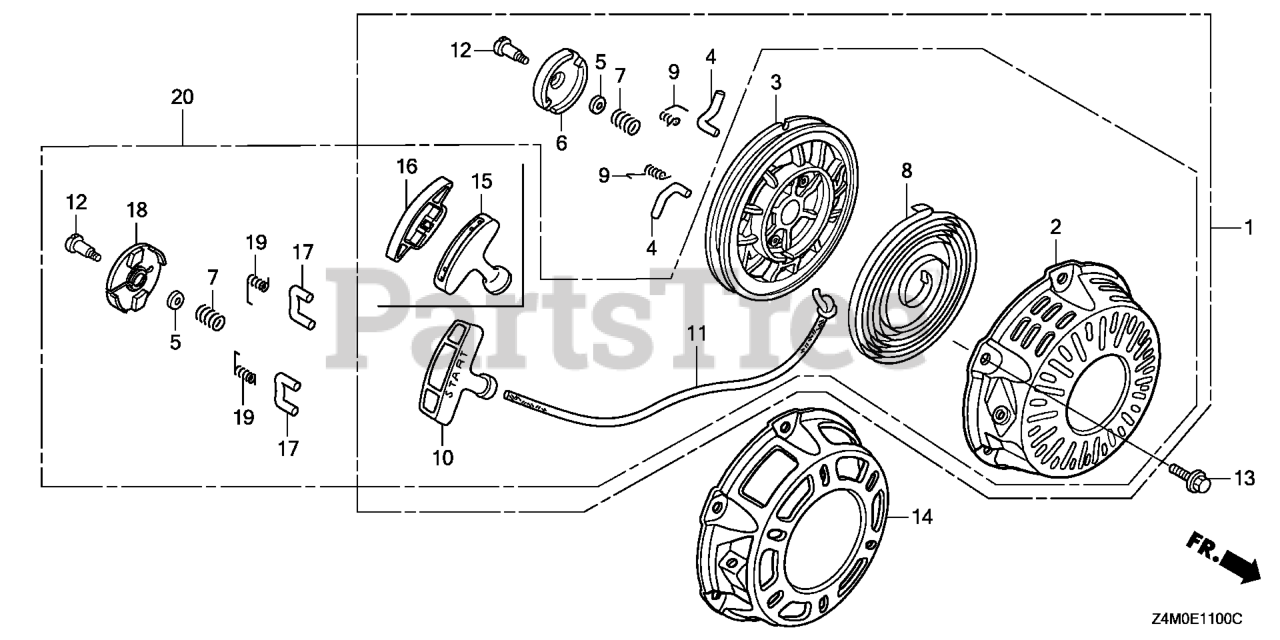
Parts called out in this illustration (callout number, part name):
2	CASE, RECOIL STARTER *R280* (POWER RED)
2	CASE, RECOIL STARTER *NH1* (BLACK)
3	REEL, RECOIL STARTER (BLACK)
5	PLATE, FRICTION
7	SPRING, FRICTION
8	SPRING, RECOIL STARTER
11	ROPE, RECOIL STARTER (#5X55")
12	SCREW, SETTING
13	BOLT, FLANGE (6X8)
15	KNOB, RECOIL STARTER
16	KNOB, REINFORCEMENT
17	RATCHET, STARTER
18	GUIDE, RATCHET
19	SPRING, RETURN
20	STARTER ASSY., RECOIL *R280* (COO)(FOR U.S.A.) (POWER RED)
20	STARTER ASSY., RECOIL *NH1* (BLACK)
